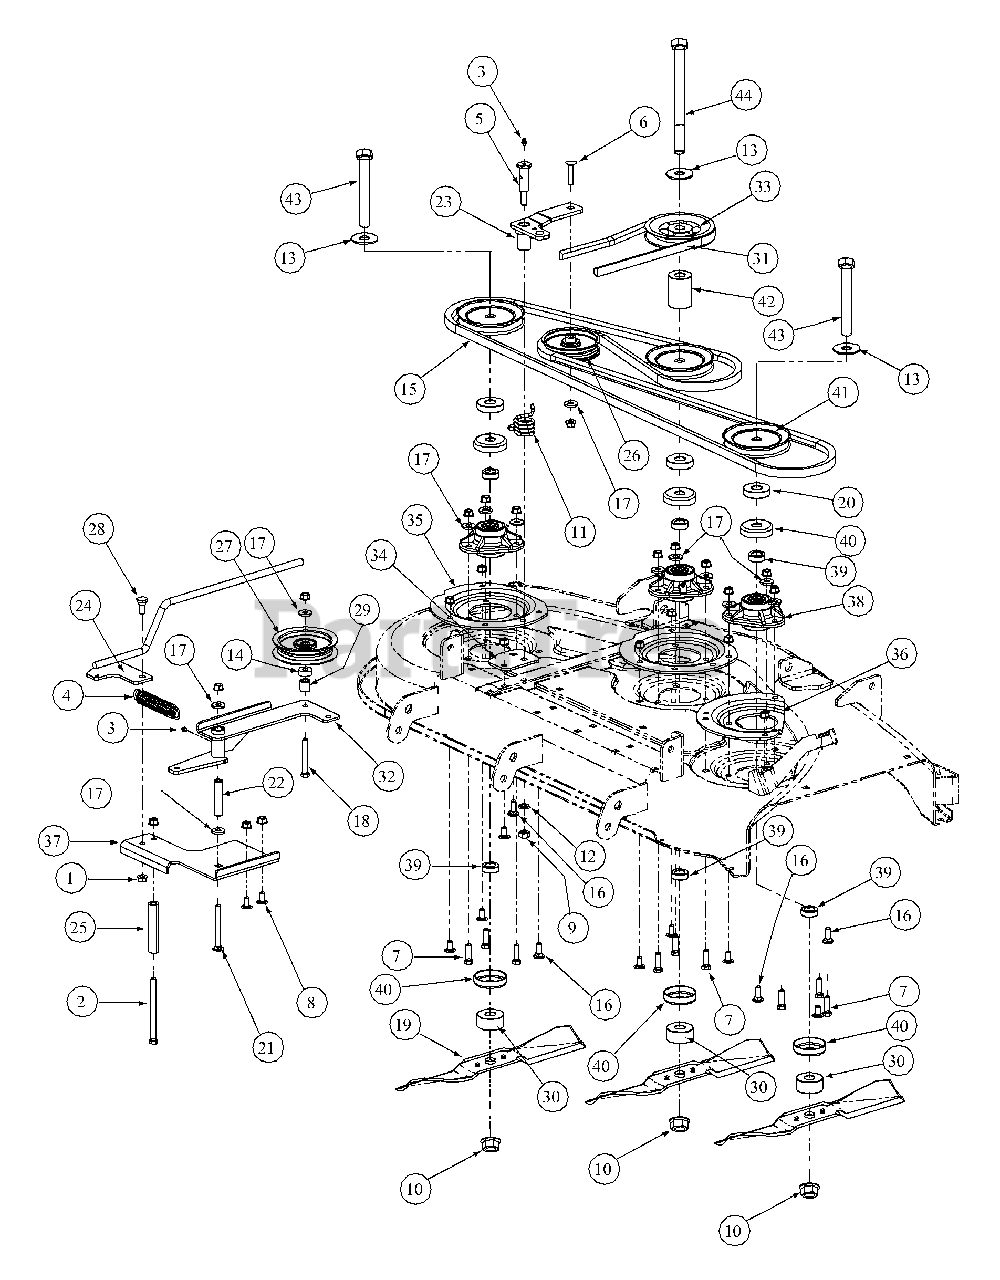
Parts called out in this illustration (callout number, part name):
1	Flange Lock Hex Nut, 3/8-16
2	Hex Capscrew, 3/8-16, 3.75
3	Grease Fitting, 1/4-28 x 3/16
4	Extension Spring, 1.0 OD x 5.125
5	Shoulder Screw, 7/16-14
6	Hex Carriage Screw, 3/8-16, 1.75
7	Hex Cap Screw, 3/8-16, 1.25
8	Carriage Bolt, 3/8-16 x .75 Lg
9	Hex Nut, 7/16-14
10	Flange Hex Nut, 3/4-16
11	Torsion Idler Spring
12	Lock Washer, 7/16
13	Flat Washer, .781 ID, 2.00 OD. 105
14	Spacer, .406 ID x 1.00 OD x .38
15	Belt, A Section x 107.3
16	Carriage Bolt, 3/8-16 x 1
17	Flat Washer, .406 ID, 1.0 OD, .105
18	Hex Capscrew, 3/8-16, 2.75
19	Mower Blade, 16.5 Lg
20	Spacer, .76ID x 2.0OD x .477
21	Carriage Bolt, 3/8-16 x 3.5 Lg
22	Spacer, .39 ID x .625 OD x 2.75
23	Idler Arm Assembly, Bearing
24	Idler Spring Rod Assembly
25	Spacer, .405 x .75 x 3.875
26	Flat Pulley with Flanges
27	Idler Pulley, 4.06 OD with Deep Flange
28	Shoulder Screw, .50 x .27 Lg; 3/8-16
29	Spacer, .385 ID x .75 OD x .875
30	Spacer, .760 ID x 2.000 OD x 0.9
31	Belt, B Section x 83.2
32	Idler Arm Assembly, Flat Top Bearing
33	Cast Pulley, 5.25 OD
34	48" Idler Arm Mounting Plate
35	Disk Reinforcement
36	Disk Reinforcement, Right Hand
37	48" Idler Arm Mounting Bracket
38	Bearing Housing Assembly
39	Spacer, .76ID x 1.25 OD x .44 Lg
40	Spindle Cup
41	Pulley, A Sect x 4.90
42	Spacer, .765 ID x 1.75 OD x 2.42
43	Hex Capscrew, 3/4-16, 5.50
44	Hex Capscrew, 3/4-16, 8.50
